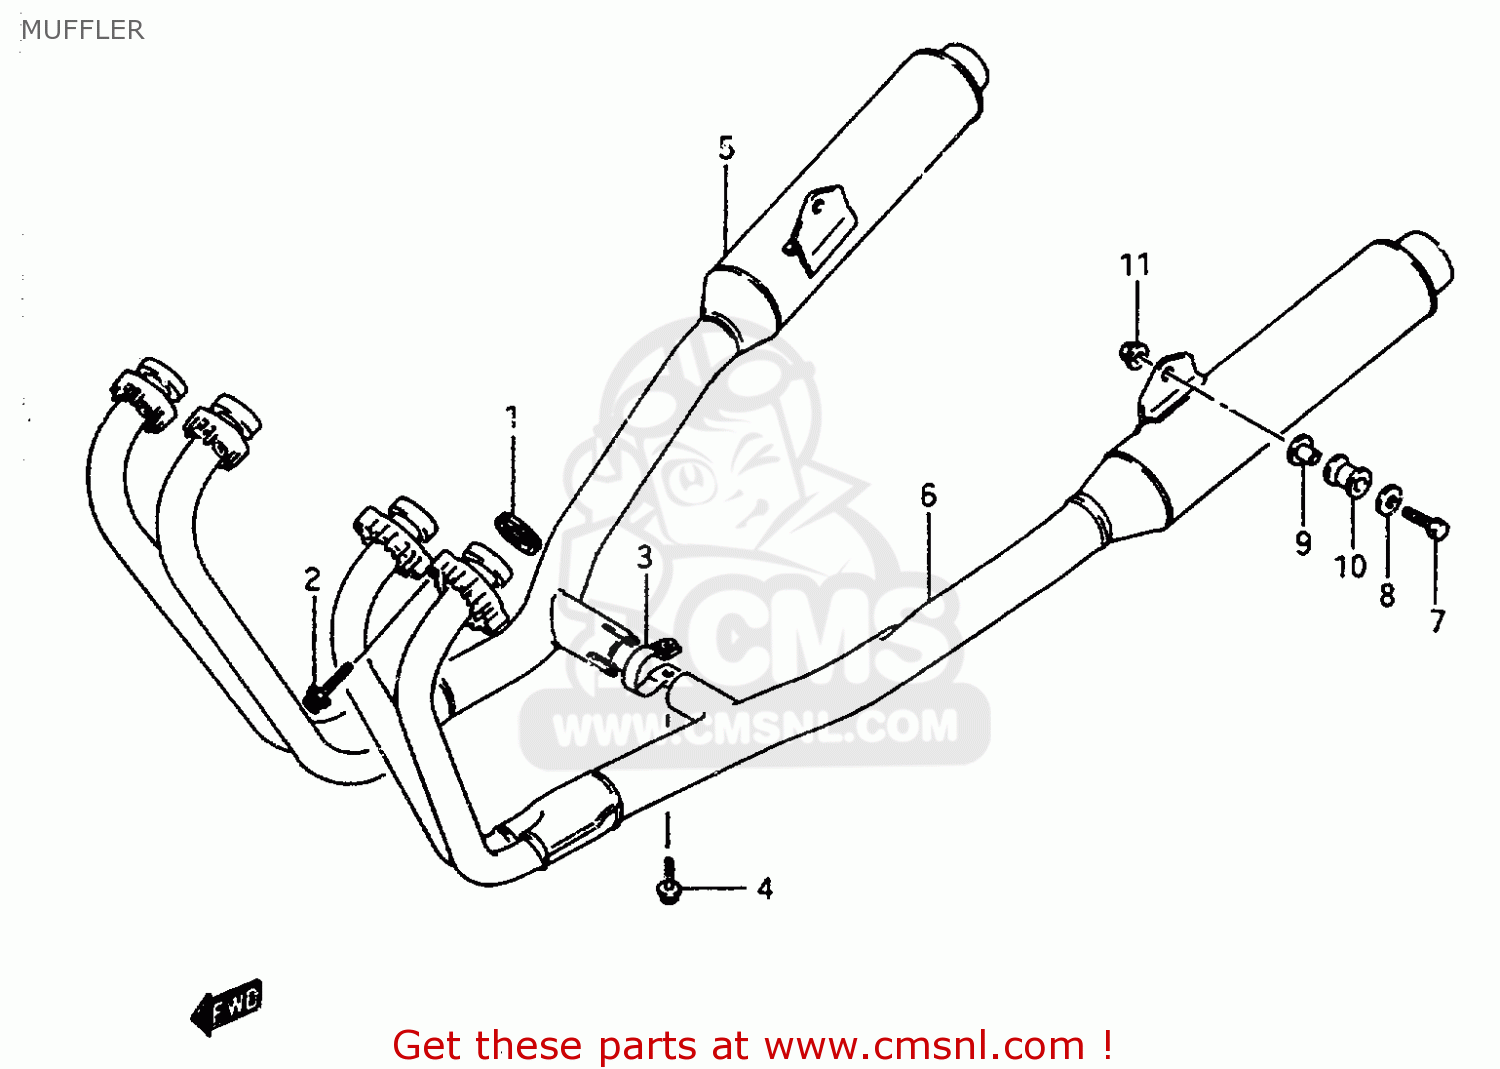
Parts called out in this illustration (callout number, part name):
1	GASKET,EXHAUST (NAS)
2	BOLT
3	CLAMP,MUFFLER CONNECTOR
4	BOLT
5	MUFFLER ASSY,R
6	MUFFLER ASSY, LH
7	BOLT(8X40)
8	WASHER (8.1X33X1.6)
9	SPACER(8.6X12X27.1)
10	CUSHION
11	NUT
